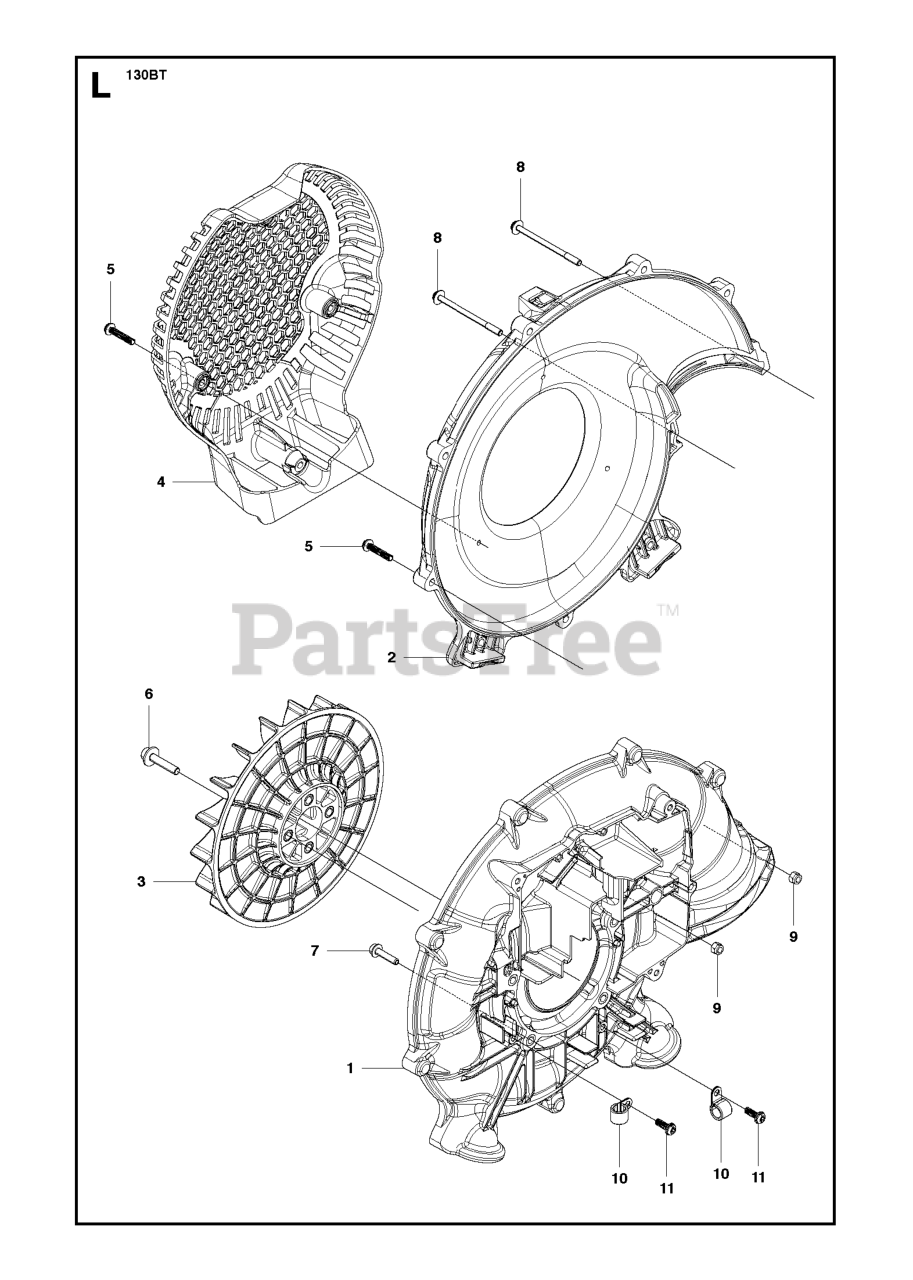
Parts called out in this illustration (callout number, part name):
7	PIN LOCATION PIN
8	SPARK PLUG HQT-7 RESISTOR
12	Husqvarna TBD
